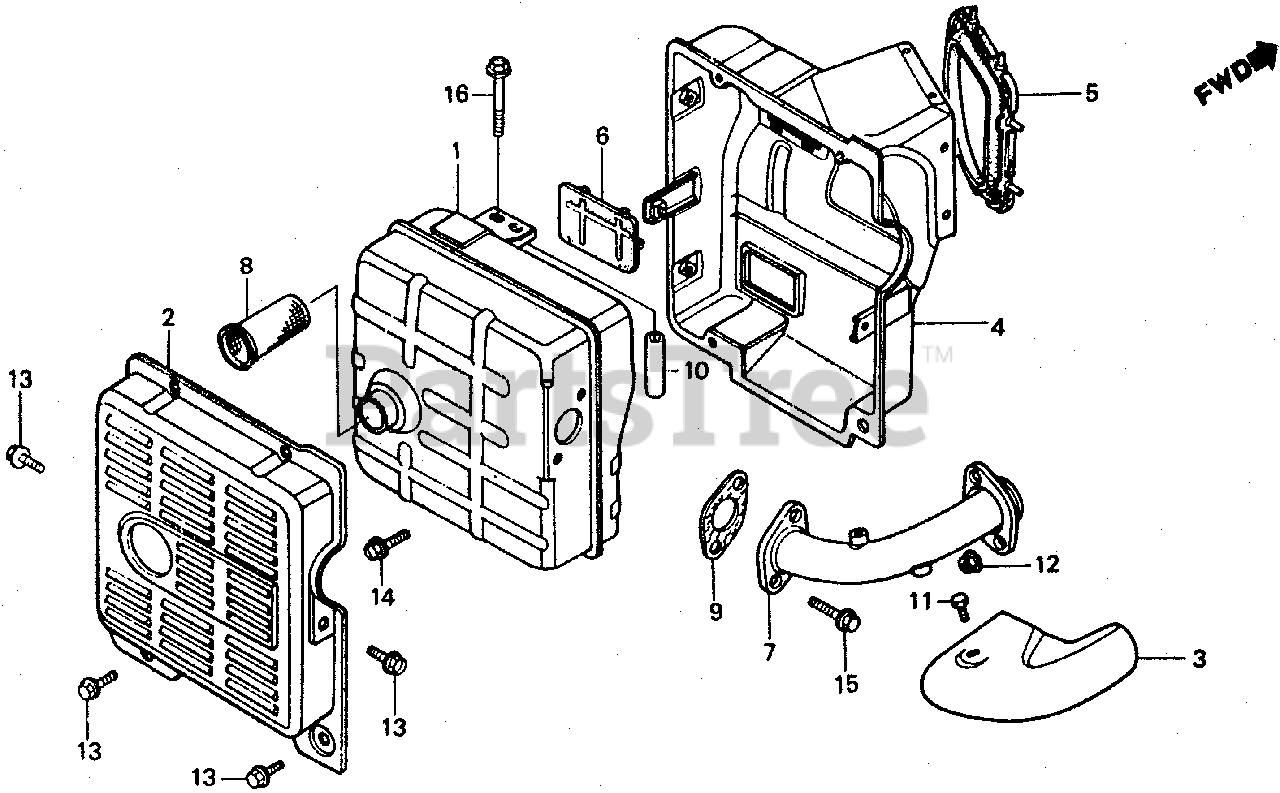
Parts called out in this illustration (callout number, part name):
1	MUFFLER (NOT AVAILABLE)
2	PROTECTOR, MUFFLER (OUTER)
3	PROTECTOR, EX. PIPE (NOT AVAILABLE)
4	PROTECTOR, MUFFLER (INNER)
5	RUBBER, PROTECTOR (INNER)
6	SEAL, MUFFLER PROTECTOR
7	PIPE, EX. (NOT AVAILABLE)
8	ARRESTER, SPARK
9	GASKET, EX. PIPE
10	COLLAR, MUFFLER
11	BOLT, HEX. (6X8)
12	NUT, FLANGE (8MM)
13	BOLT, FLANGE (6X10)
14	BOLT, FLANGE (8X16)
15	BOLT, FLANGE (8X20)
16	BOLT, FLANGE (8X45)
